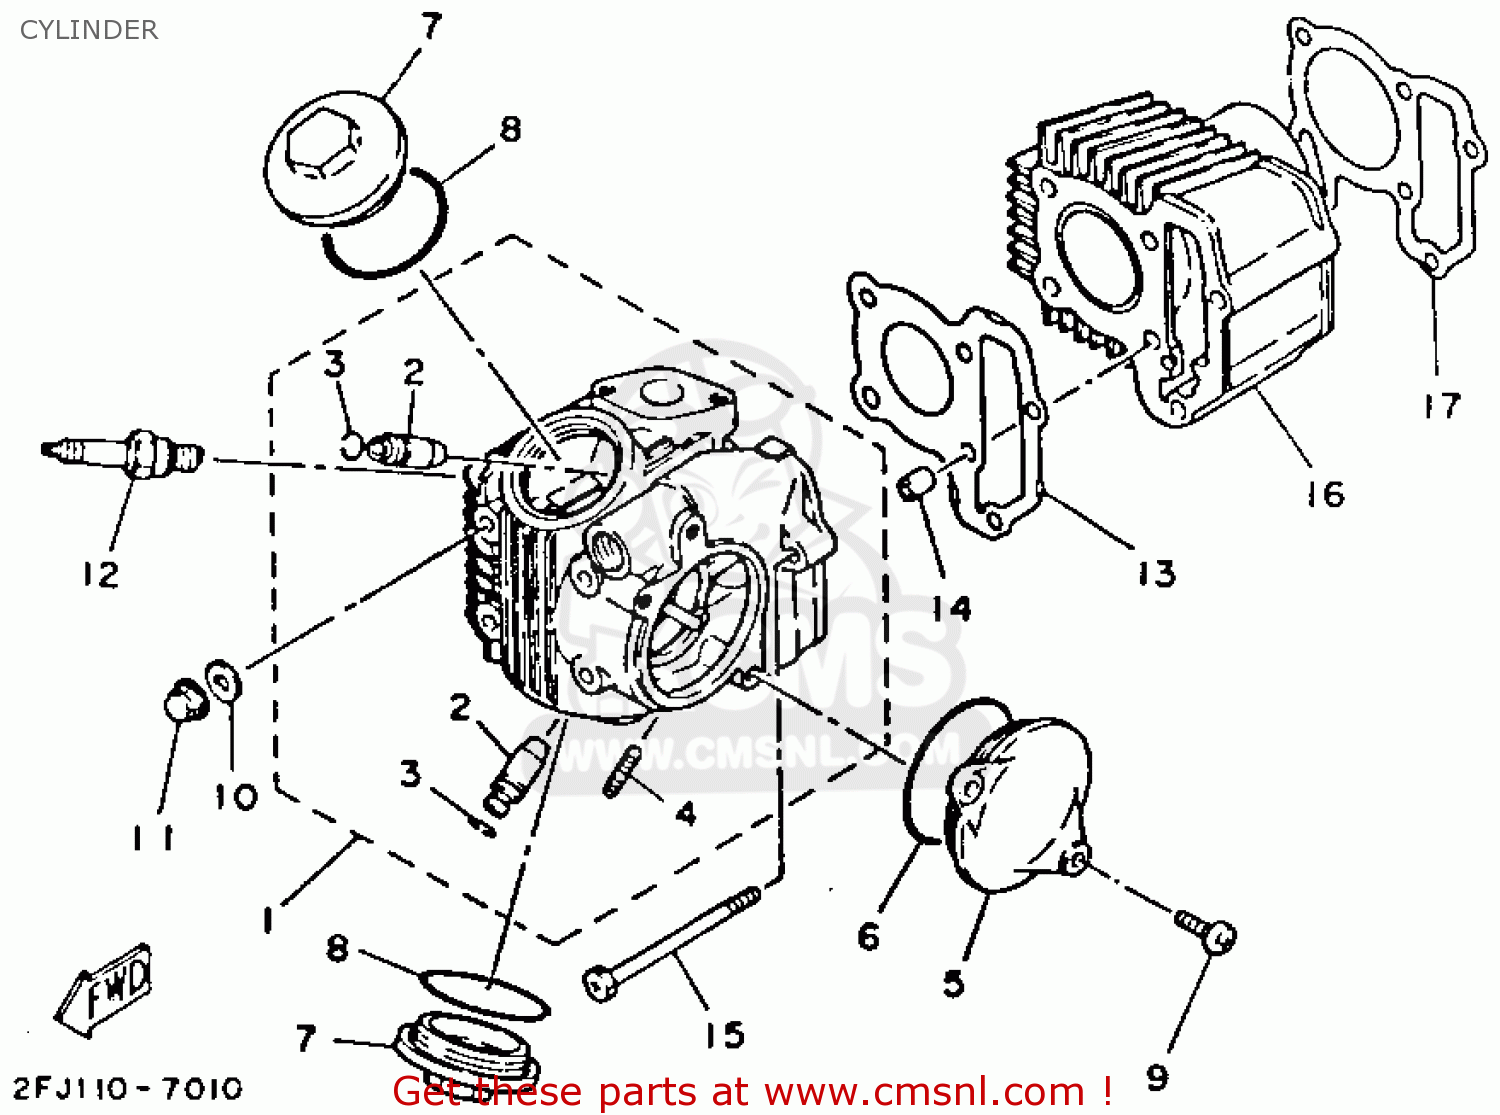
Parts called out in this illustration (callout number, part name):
1	CYLINDER HEAD ASSY
2	GUIDE, EXHAUST VALVE (1ST O/S)
3	CIRCLIP (22F)
4	BOLT
5	COVER, CYLINDER HEAD SIDE 1
6	O-RING (22F)
7	COVER, CYLINDER HEAD SIDE 2
8	O-RING(55X)
9	SCREW PAN HEAD
10	WASHER, PLATE (22F)
11	NUT, CROWN (21G)
12	PLUG SPARK UR
13	GASKET, CYLINDER HEAD 1 (NAS)
14	P1N, DOWEL
15	BOLT, FLANGE(55X)
16	CYLINDER 1
17	GASKET, CYLINDER (NAS)
